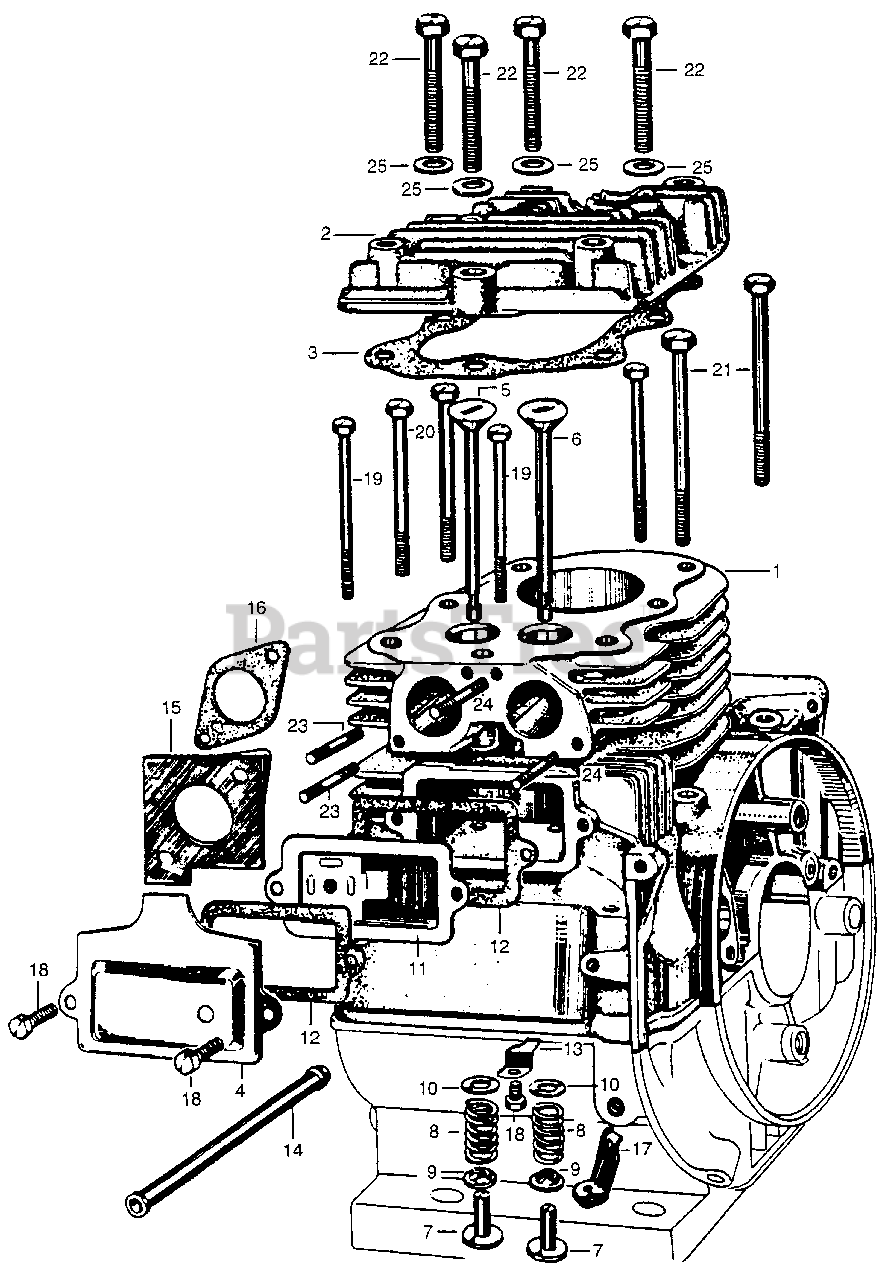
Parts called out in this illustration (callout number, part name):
1	CYLINDER
2	CYLINDER HEAD
3	GASKET, CYLINDER HEAD (NOT AVAILABLE)
4	COVER, TAPPET
5	VALVE, IN. (NOT AVAILABLE)
6	VALVE, EX. (NOT AVAILABLE)
7	LIFTER, VALVE
8	SPRING, VALVE
9	RETAINER, VALVE SPRING
10	SEAT, VALVE SPRING
11	PLATE, BREATHER (NOT AVAILABLE)
12	GASKET, BREATHER CASE (NOT AVAILABLE)
13	SEPARATOR, OIL
14	PIPE, BREATHER
15	INSULATOR, CARBURETOR (NOT AVAILABLE)
16	GASKET, CARBURETOR INSULATOR (NOT AVAILABLE)
17	HOLDER, WIRE
18	BOLT, HEX. (6X12)
19	BOLT, HEX. (6X70)
20	BOLT, HEX. (8X70)
20	BOLT, HEX. (8X70) (NOT AVAILABLE)
21	BOLT, HEX. (8X95)
22	BOLT, HEX. (10X50)
23	BOLT, STUD (6X25)
24	BOLT, STUD (6X18)
25	WASHER, PLAIN (10MM)
